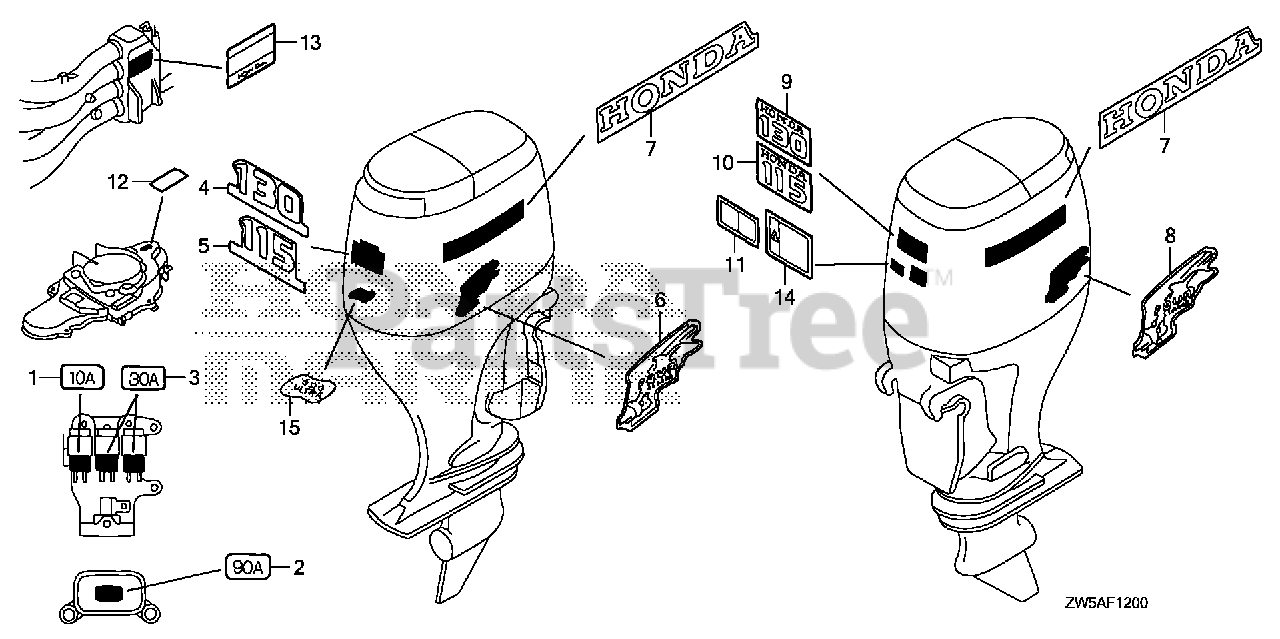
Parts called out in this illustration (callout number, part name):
1	MARK, FUSE (10A)
2	MARK, FUSE (90A)
3	MARK, FUSE (30A)
5	MARK, RR. (BF115)
6	MARK, SIDE (R. SIDE)
7	MARK, SIDE STRIPE (HONDA)
8	MARK, SIDE (L. SIDE)
10	MARK, FR. EMBLEM (BF115)
12	LABEL, OIL CAUTION (ENGLISH)
13	MARK, MUFFLER
14	LABEL, OPERATOR CAUTION (ENGLISH)
14	LABEL, WARNING OPERATOR
